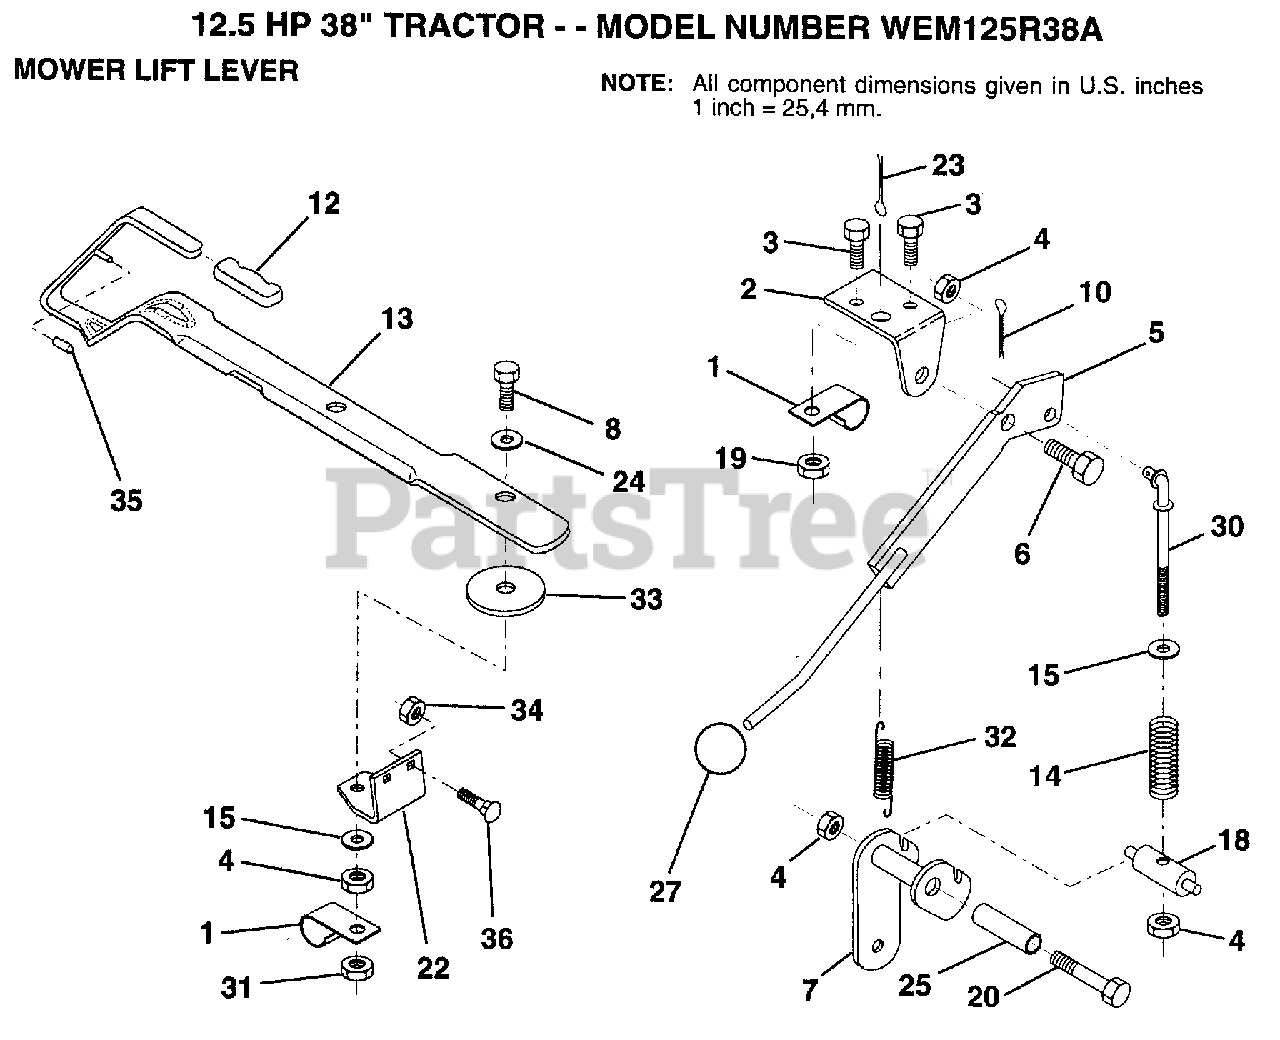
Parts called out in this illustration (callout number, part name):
1	"CLIP,INSULATOR"
2	BRKT CLUTCH
3	BOLT
4	NUT
5	CLUTCH LEVER AS
6	"BOLT, SHOULDER LT"
7	ARM.CLUTCH.ASM
8	BOLT
10	COTTER PIN
12	GRIP HANDLE
13	LEVER LIFT LR
14	COMP CLUTCH SPRNG
15	WASHER HYT
18	TRUNNION
20	BOLT
22	LIFT LEVER BRKT
24	WASHER
25	TUBE SPACER
27	KNOB.DUCKHEAD.1/2
30	ROD TENSION CLUTC
31	LOCKNUT
32	SPRING EXT
33	WASHER
34	NUT
35	VINYL CAP RED
36	BOLT
